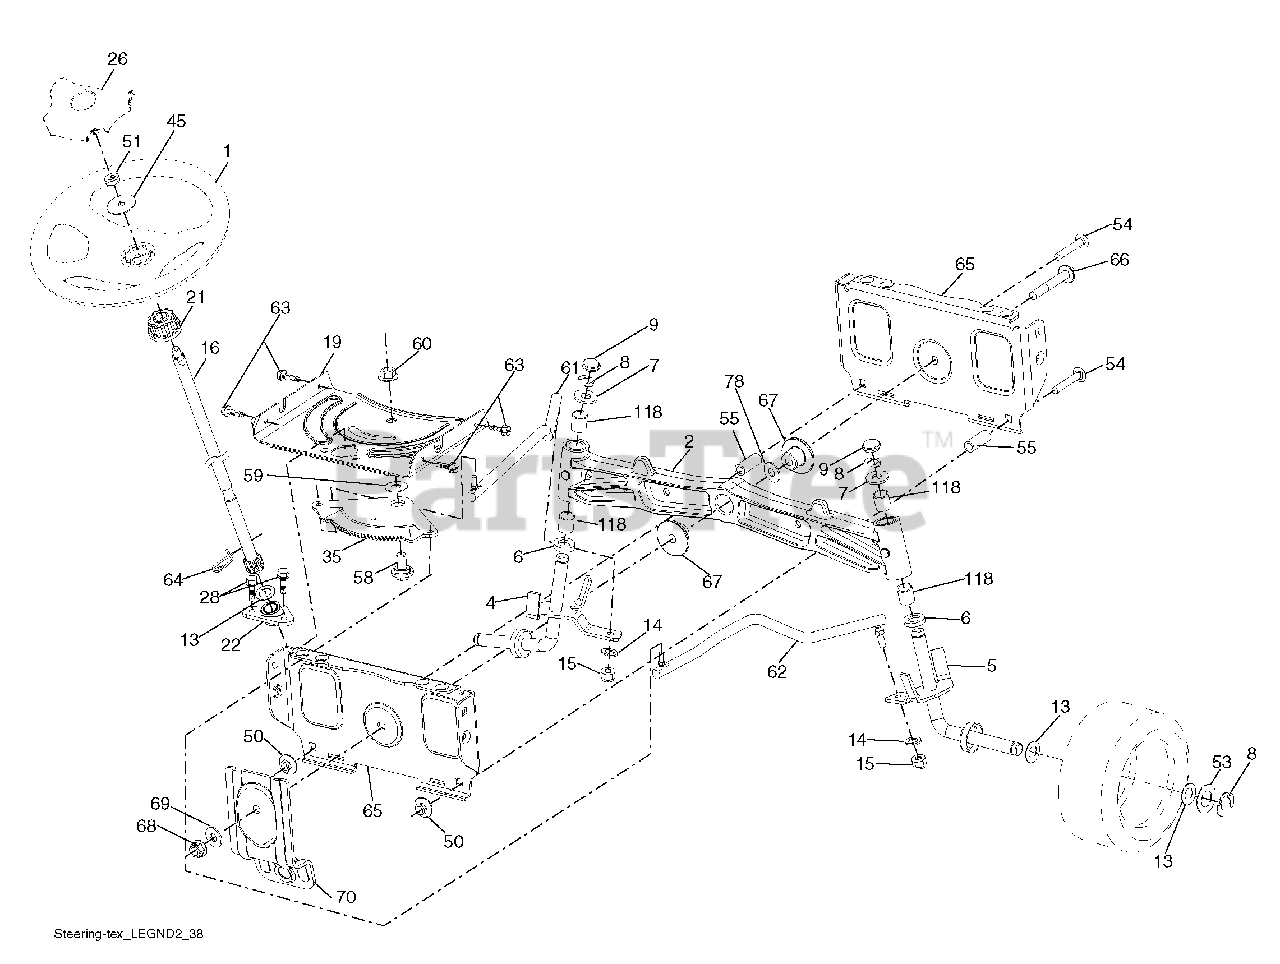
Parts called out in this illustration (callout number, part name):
1	Wheel, Steering
2	Axle Asm., Front
4	Spindle Asm., LH
5	Spindle Asm., RH
6	Bearing, Race Thrust Harden
7	Washer 25/32 x 1-5/8 x 16 Ga.
8	Ring, Klip #T5304-75
9	Cap, Spindle
13	Washer 25/32 x 1-1/4 x 16 Ga.
14	Washer, Lock Hvy Hlcl Spr 3/8
15	Nut, Crown Lock 3/8-24 unf
16	Shaft Steering
19	Plate Steering
21	Adapter, Wheel Steering
22	Strg. Supt. Lower
26	Insert, Wheel Steering
28	Screw 3/8-16 x 3/4
35	Gear, Sector Plate
45	Washer 9/16 x 2-3/8 x 12 Ga.
50	Nut Lock Flg. 3/8-16 unc
51	Nut Hex Jam Toplock 1/2-20 unf
53	Washer Hardened .793 x 1.637 x .060
54	Bolt Hex Hs 3/8-16 unc x 2-1/4
55	Spacer Brace Axle
58	Bolt Shoulder Sector Pivot CFM
59	Washer Thrust Sector Steering
60	Nut Flange Lock 5/8-11
61	Draglink, LH
62	Draglink, RH
63	Screw 5/16-18 x 3/4
64	Retainer Clip Spring Steering
65	Brace Axle Front
66	Bolt Hex Fghd 7/16-14 x 3 Serr
67	Bushing PM Front Axle
68	Nut Lock Flange 7/16-14 Gr. 5
69	Washer 1.5 x .505 x .118
70	Bracket Deck Susp. Front
78	Washing Thrust
